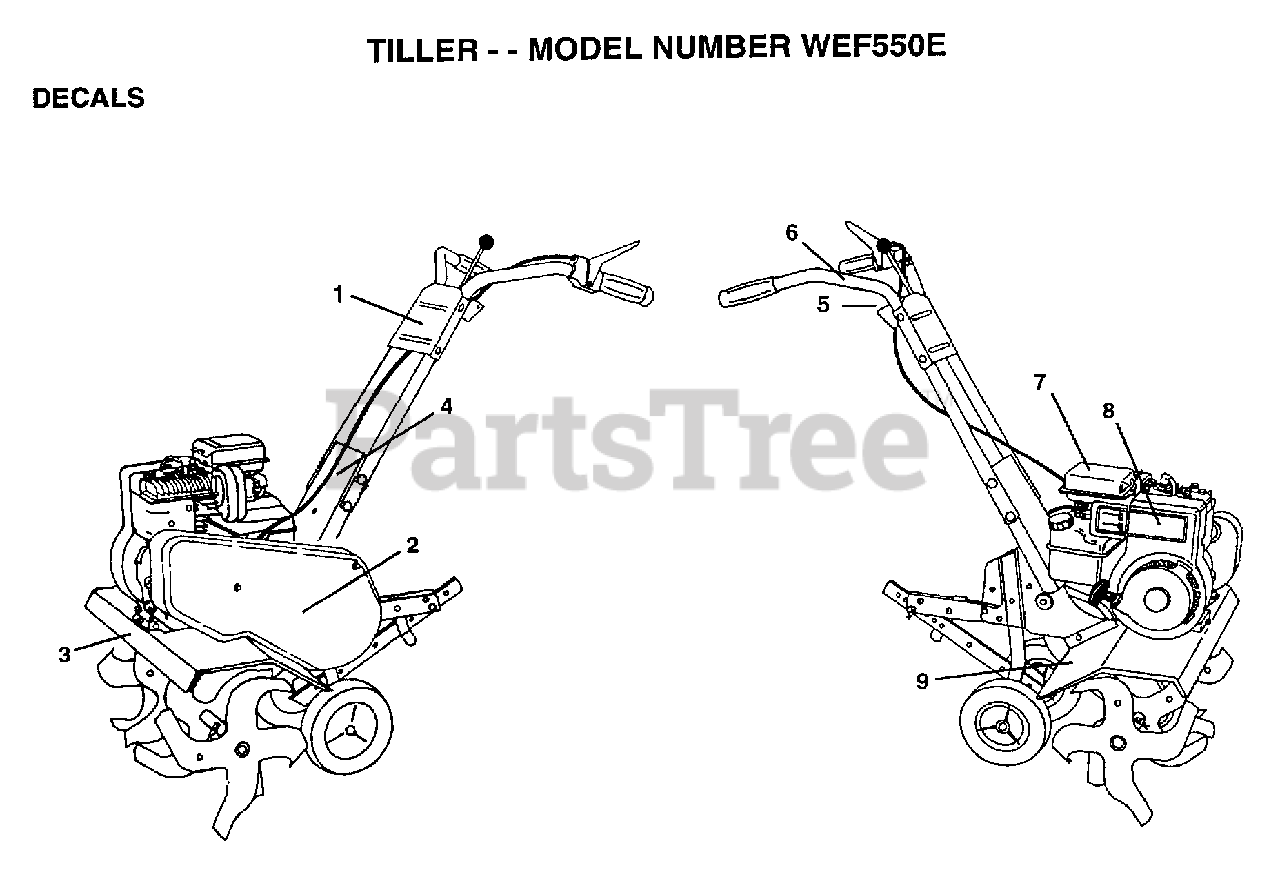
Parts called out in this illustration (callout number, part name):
2	DECAL BELTGUARD
3	DECAL.SHIELD.TINE
4	DECAL.PNL.HANDLE
5	DECAL REVERSE
6	DECAL TI
7	DECAL TI
8	DECAL, BRIGGS & STRATTON
